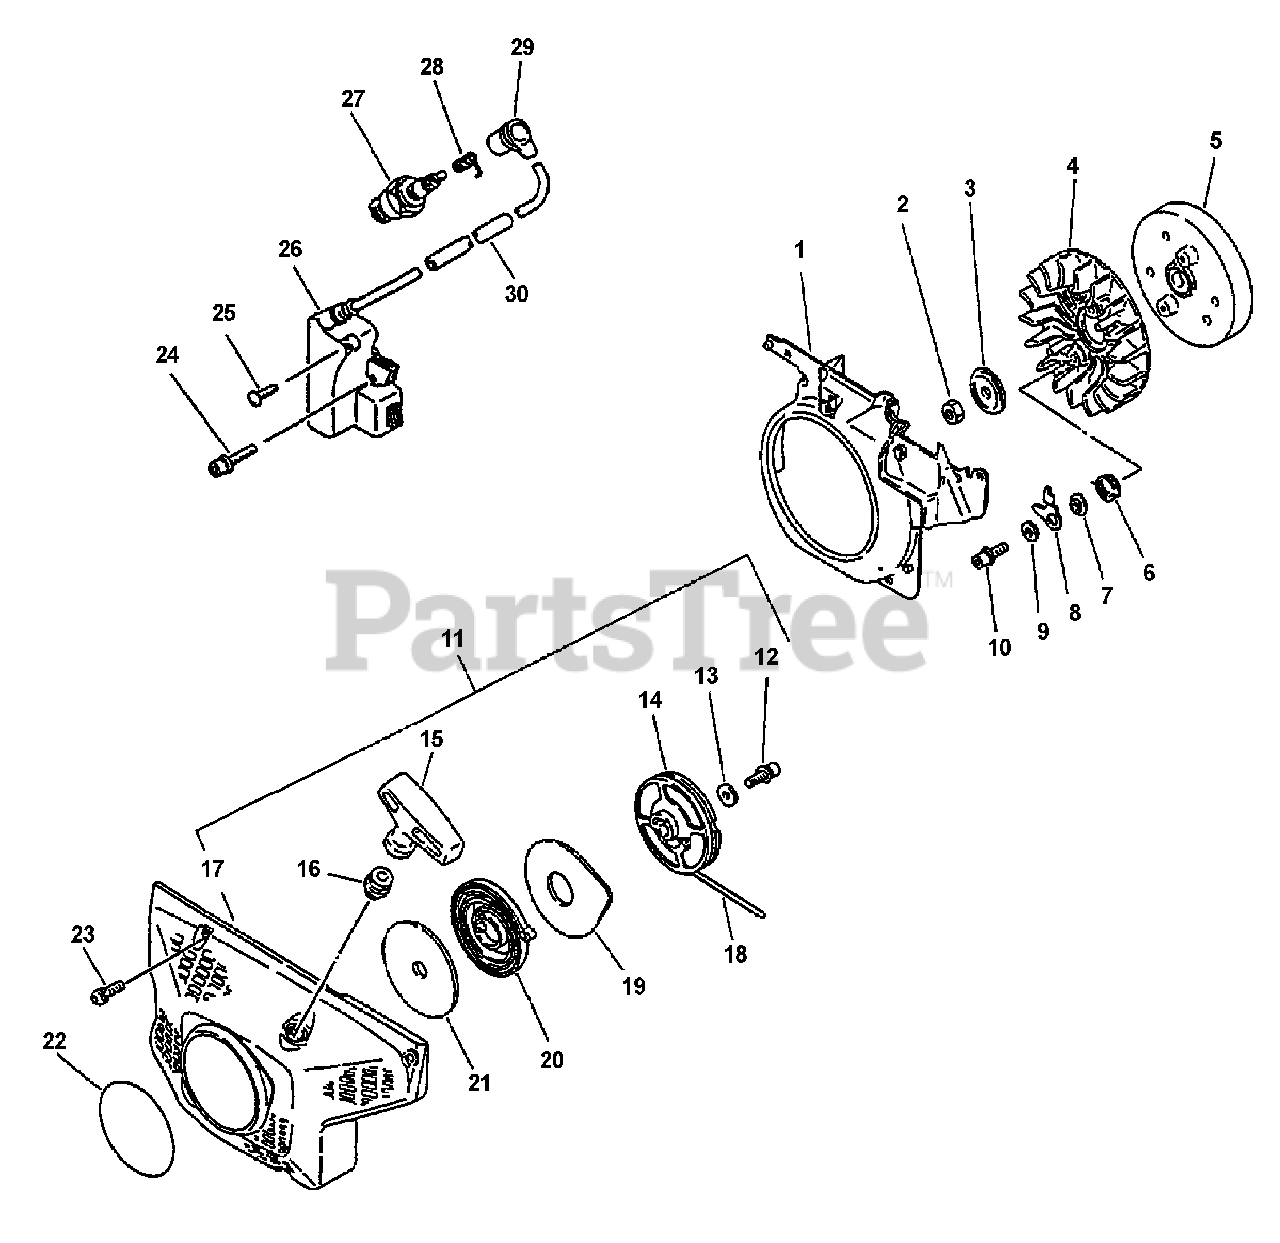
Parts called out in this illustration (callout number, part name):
1	SHIELD, FAN
3	WASHER - CUP
5	FLYWHEEL
6	SPRING, RETURN
8	PAWL, STARTER
9	WASHER - 5
10	SCREW - 5X14
11	STARTER ASSY
12	SCREW - 5X14
13	WASHER - 5
14	REEL, ROPE
15	GRIP, STARTER
16	GUIDE, ROPE
17	CASE, STARTER
18	RePower BULK ROPE - 200 FEET
19	PLATE, STARTER
20	SPRING, REWIND
21	PLATE, STARTER
22	LABEL - ECHO
23	SCREW - 5X20
24	SCREW - 4X20
25	SCREW - 4X8
26	COIL, IGNITION
27	SPARK PLUG -- CJ-6Y
28	TERMINAL, SPARK PLUG CAP
29	CAP, SPARK PLUG
30	TUBE
